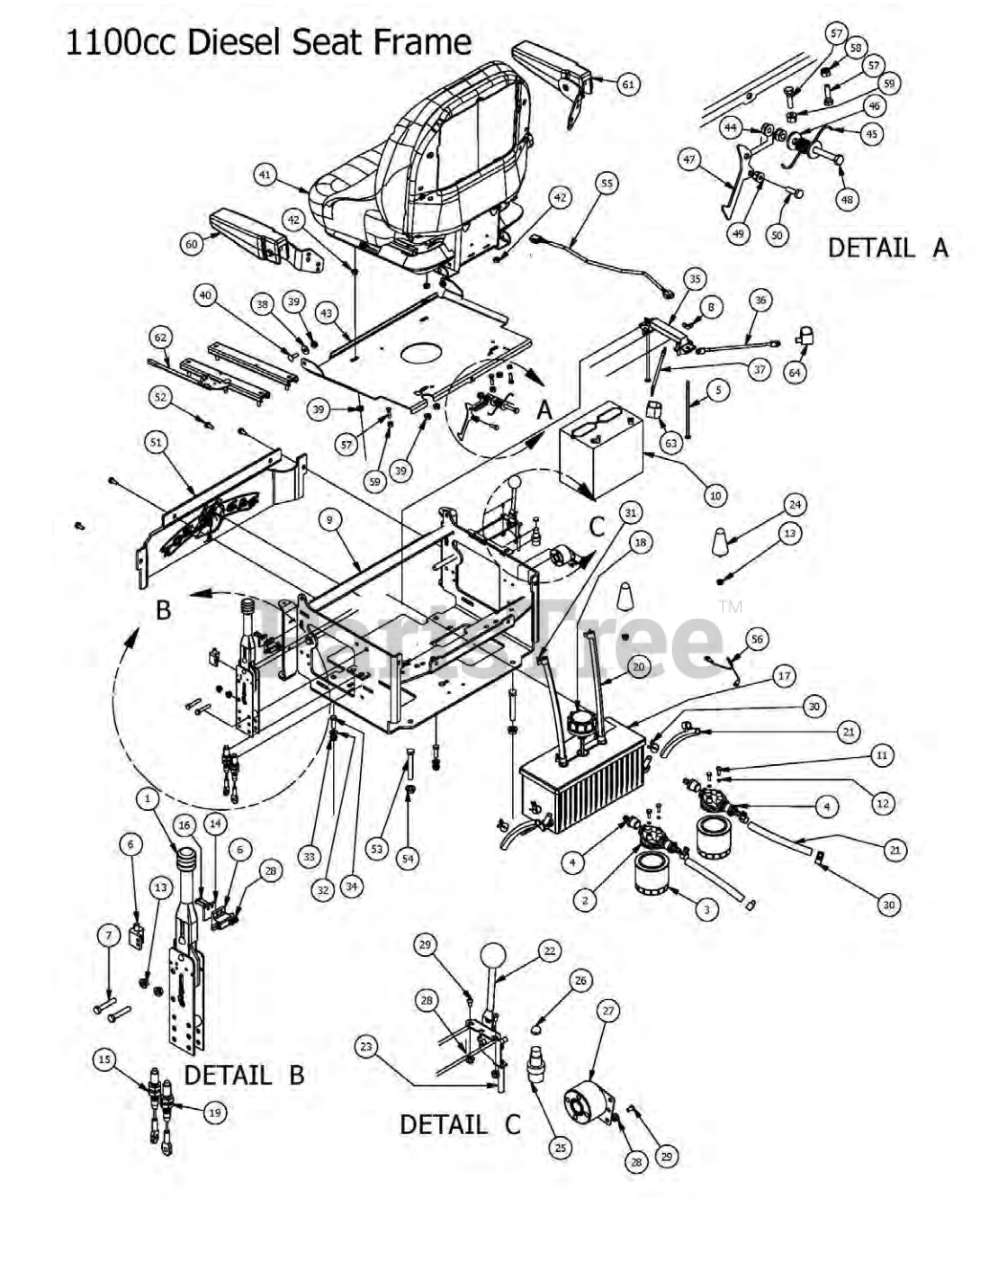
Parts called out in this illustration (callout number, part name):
1	Hand Brake Assembly
2	Filter Head
3	Hydraulic filter
4	Filter Head Fitting
5	1/4-20 X 9 Carriage Bolt
7	5/16" x1 3/4" Hex Balt
8	1/4" Wing Nut
9	2007 Diesel Seat Frame
10	Battery Diesel Models -151
11	1/4" x 3/4" Hex Bolt
12	1/4" Lock Washer
13	5/16" Flange Nut w/Serrations
14	Switch Block Plastic
15	Short Brake Cable
16	1024 x 1" Allenhead Bolt
17	Aluminum Hydraulic Tank
18	Hydraulic Tank Cap
19	Long Brake Cable
20	3/8" x 32" Clear Hose
21	1/2" x 9 1/4" Braided Hose
22	Throttle Diesel
23	Diesel Throttle Cable Only
24	Spring Cushion
25	Momentary Start Switch
26	Start Switch Boot - Diesel
27	Heat Warning Piezo Buzzer
28	#10 Nylock Nut
29	1024 x 5/8 Buttonhead Bolt
30	1/2 Hose Clamp
31	3/8 hose clamp
32	3/8" Flat Washer
33	3/8" Flange Nut
34	3/8" x 1 1/4" Hex Bolt
35	Battery Hold Down
36	Black Battery Cable - Diesel
37	Red Battery Cable - Diesel
38	360 ID Plastic Washer
39	5/16-18 Nylon Flange Nut
40	5/16" x 1" Carriage Bolt
41	Grammer Suspension Seat w/ Seat Belt
42	5/16" Flange Nut
43	Seat Plate
44	5/16-18 Nylon Flange Nut
45	Torsion Spring for Seat latch
46	.360 ID Plastic Washer
47	Seat Latch Lever
48	5/16-18 X 2 Hex C/S (GR.5) ZC
49	1/4-20 Nylon Insert flange Nut
50	1/4-20 x 1-1/4 GR 5 Hex Bolt
51	Cooler Cover
52	5/16 x 3/4 washer head type Fscrew
53	1/2 x 3 1/2 Flange Bolt Grade 8
54	1/2" Flange Nut
55	Seat Switch Adapter
56	Seat Cable
57	1/4-20 x 1 GR 5 hex bolt zinc
58	1/4 Nylock Nut
59	1/4-20 Nylon Insert flange Nut
60	Left Armrest Kit for Grammer Seat
61	Right Armrest Kit for Grammer Seat
62	Rails for Grammer Seat (Pair)
64	Black Boot For Ground Cable
